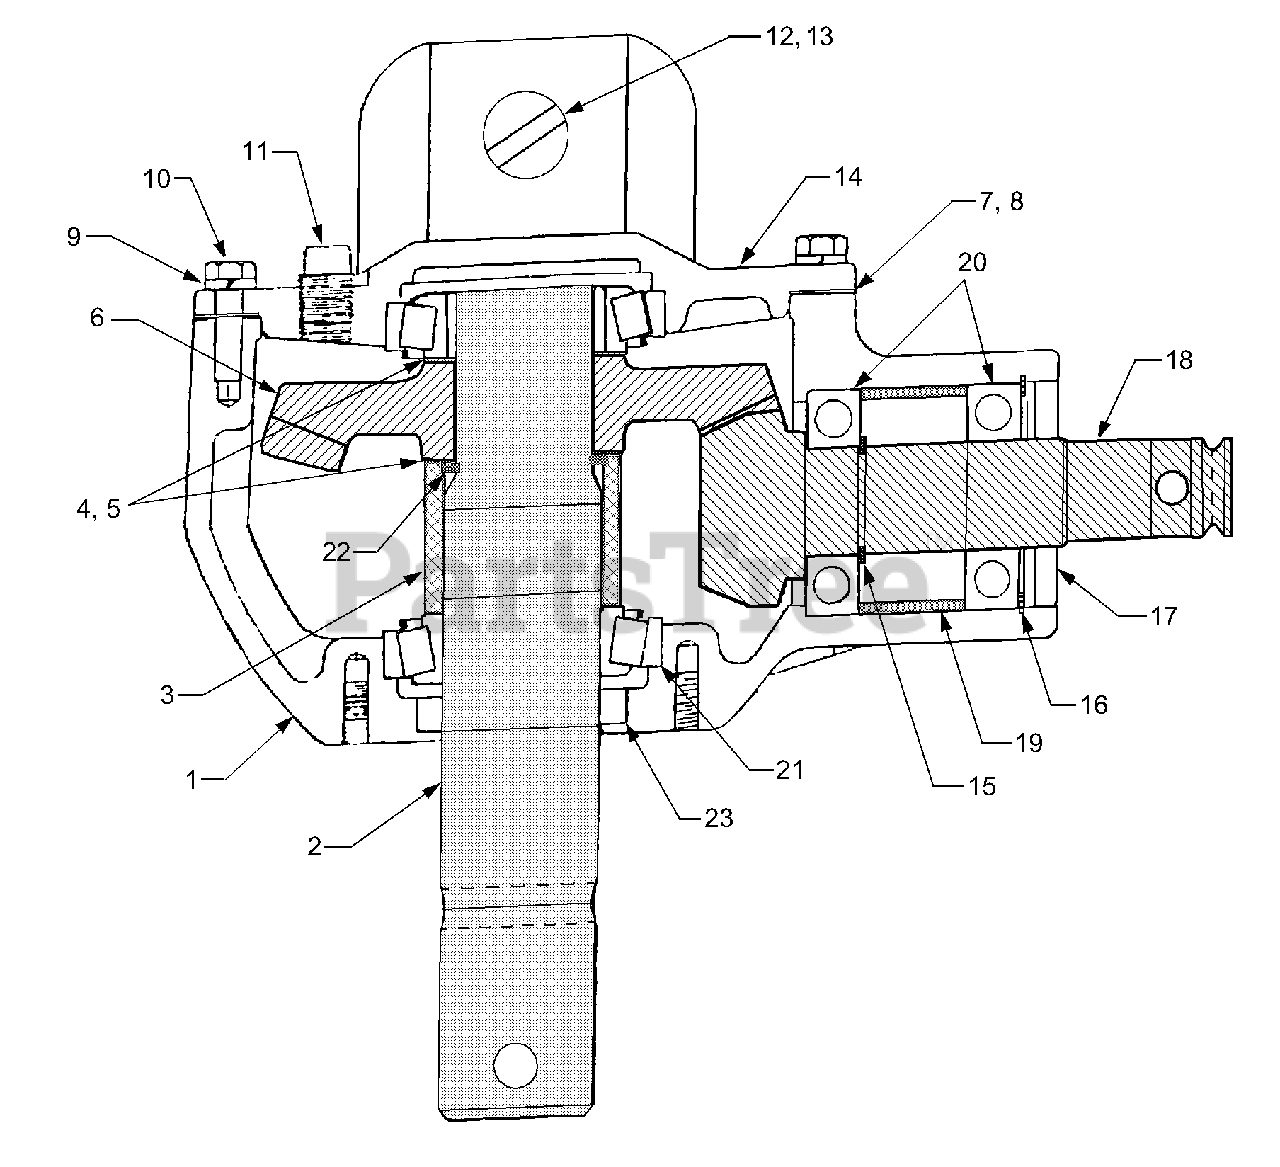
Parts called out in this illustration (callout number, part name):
2	Output Shaft
3	Output Bearing Spacer
4	Shim, Output Gear, .03
5	Shim, Output Gear, .50
6	Output Gear - 33 Tooth
7	Gasket, Cap Shim, .10
8	Gasket, Cap Shim, .25
9	Lock Washer, M10
10	Hex Cap Screw, M10 x 30
11	Pipe Plug, 1/2"
12	Hanger Shaft
15	Retaining Ring
16	Retaining Ring
17	Seal, Input Shaft
18	Pinion Shaft and Gear, 11 Tooth
19	Bearing Spacer
22	Retaining Ring
23	Seal, Output Shaft
